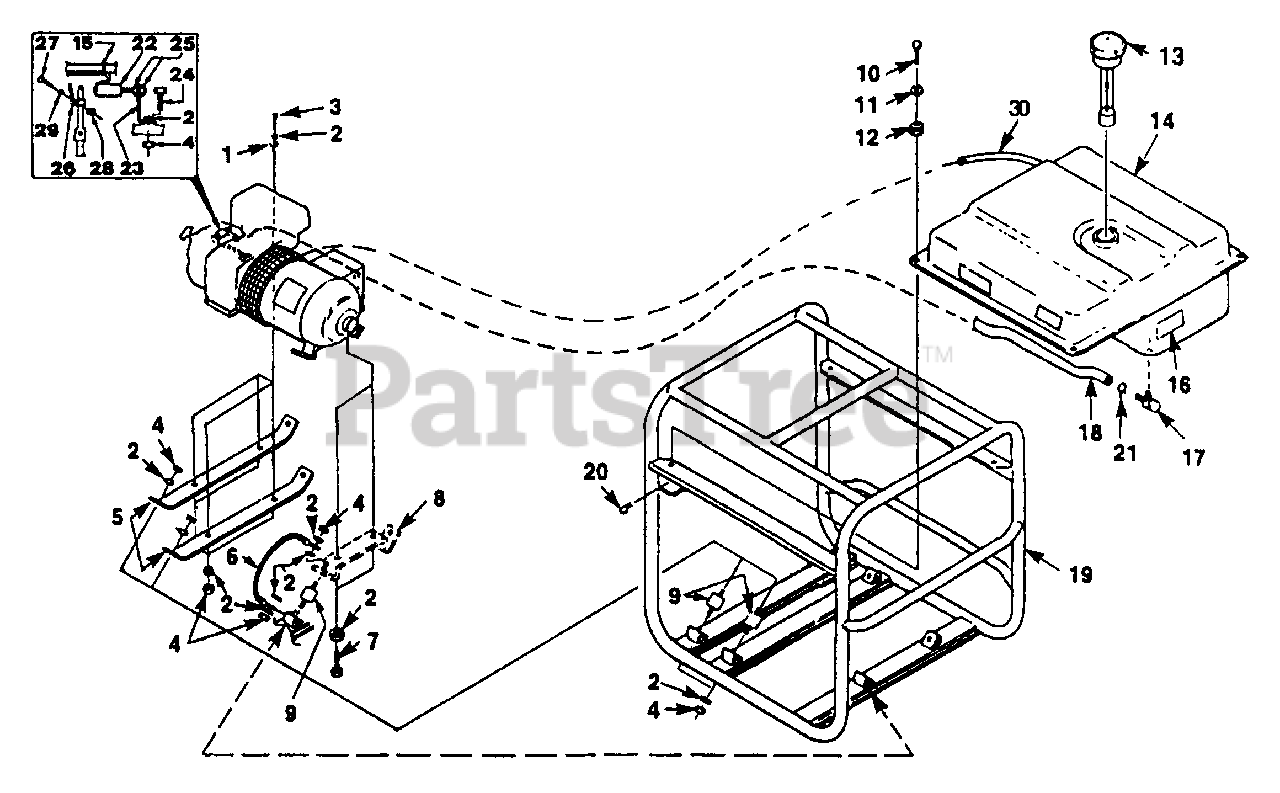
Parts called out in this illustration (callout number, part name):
1	WASHER - Flat (5/16)
2	WASHER - Lock/Int (5/16)
3	SCREW - Cap Hex Hd (5/16-18 X 2")
4	NUT - Hex (5/16-18)
5	SUPPORT - Engine
6	GROUND STRAP
7	SCREW - Thread Form (5/16-18 X 1")
8	SUPPORT - Generator
9	ISOLATOR - Vibration
10	PIN - Clevis
11	WASHER - Flat (1/4)
12	GROMMET - Isolator
13	CAP - Fuel
14	TANK - Fuel
15	TIE - Cable
16	DECAL - Fuel Valve
17	VALVE - Fuel
18	FUEL LINE
19	ROLL CAGE
20	PIN - Cotter Hair
21	HOSE - Clip
22	ELECTROMAGNET W/Grommet
23	BRACKET - Magnet, 11HP
24	SCREW - Cap Hex Hd (5/16-18 X 1")
25	NUT - Hex (1/4-28)
26	PADDLE - 11HP
27	SCREW - Mach Pan Hd (8-32 X 2/3")
28	NUT - Speed (8-32)
29	WASHER - Lock/Int (#8)
30	ELECTRICAL LEAD
